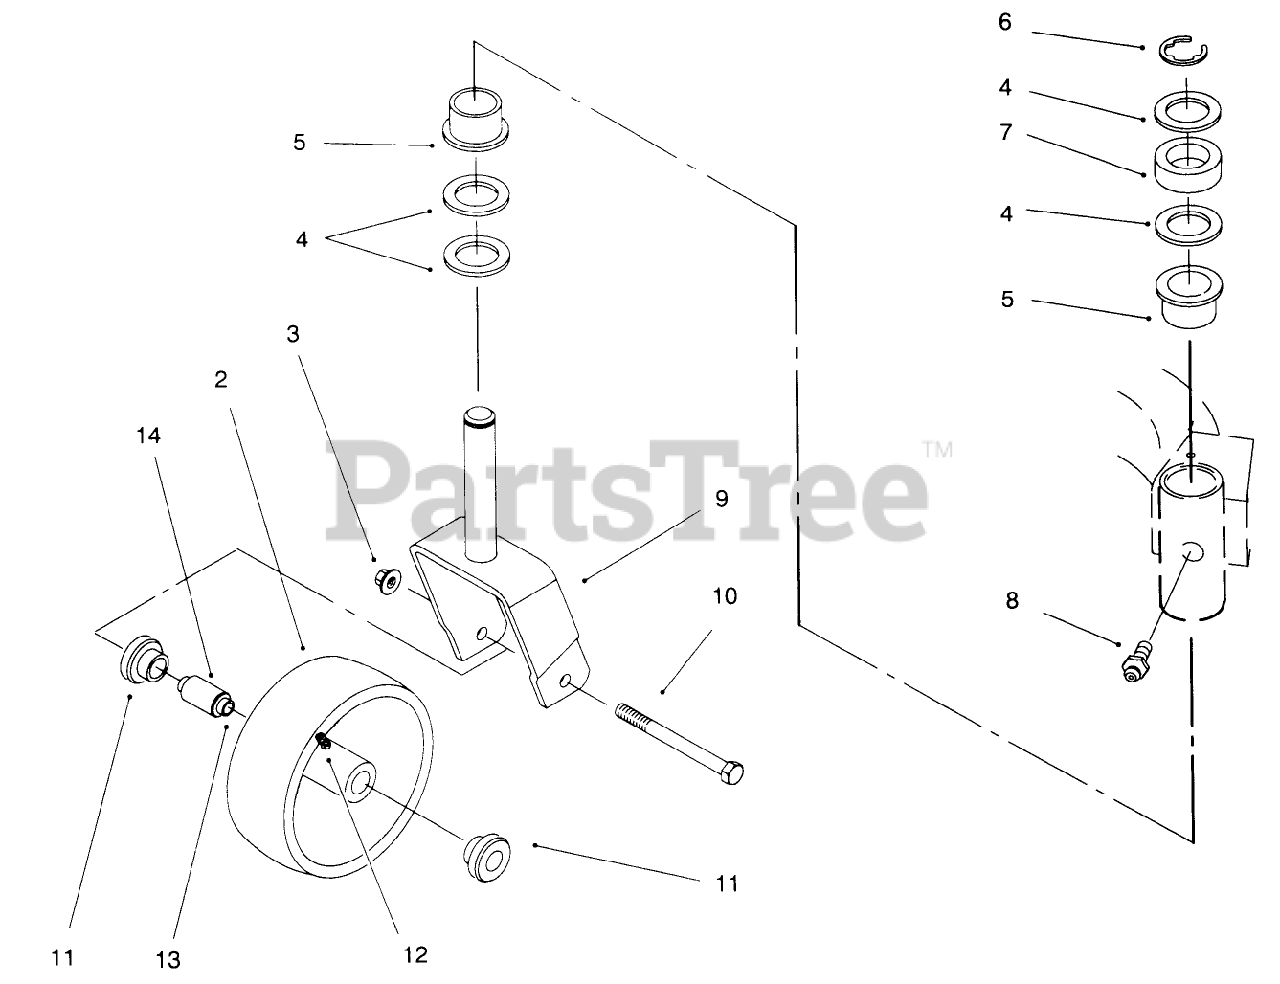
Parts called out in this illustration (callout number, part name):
3	NUT-HEX
4	WASHER-THRUST
5	BUSHING
6	RING-RETAINING
7	SPACER-CASTOR
8	FITTING-GREASE
9	Fork-Castor
10	SCREW-HH
11	BEARING-OUTSIDE
12	FITTING-GREASE, 90 DEG
13	SPANNER
14	TIMING ROD
22	Wheel & Tire Assembly (Incl. Ref. #1 &11-13)
